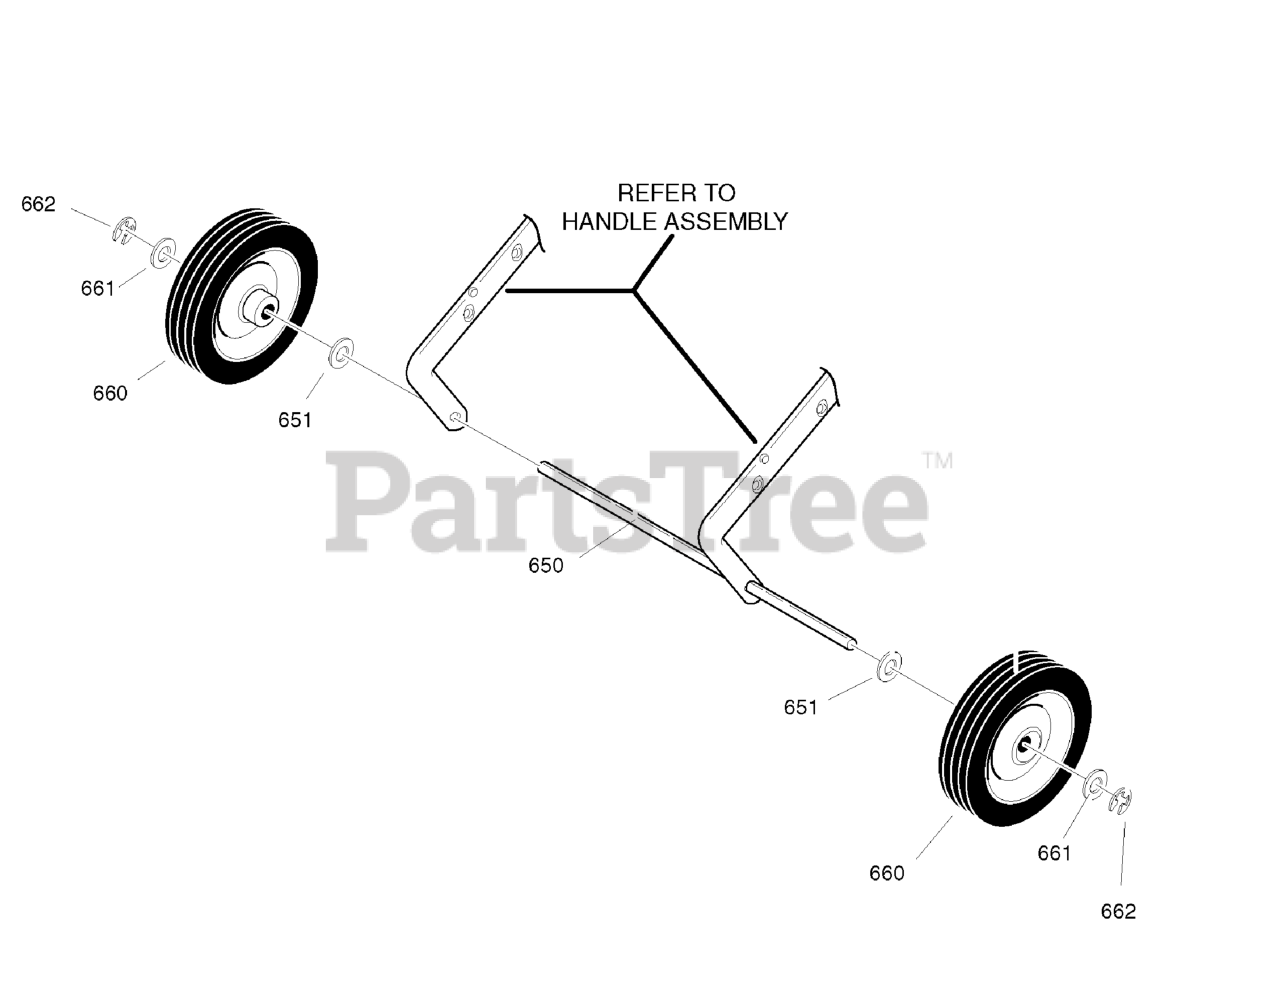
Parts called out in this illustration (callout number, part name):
650	AXLE, 20.53 WHL 20/21
651	WASHER, FLAT .391 X 1.00 X .125
660	TIRE & RIM
661	WASHER, FLAT .391 X 1.00 X .125
662	RING, RETAINER
